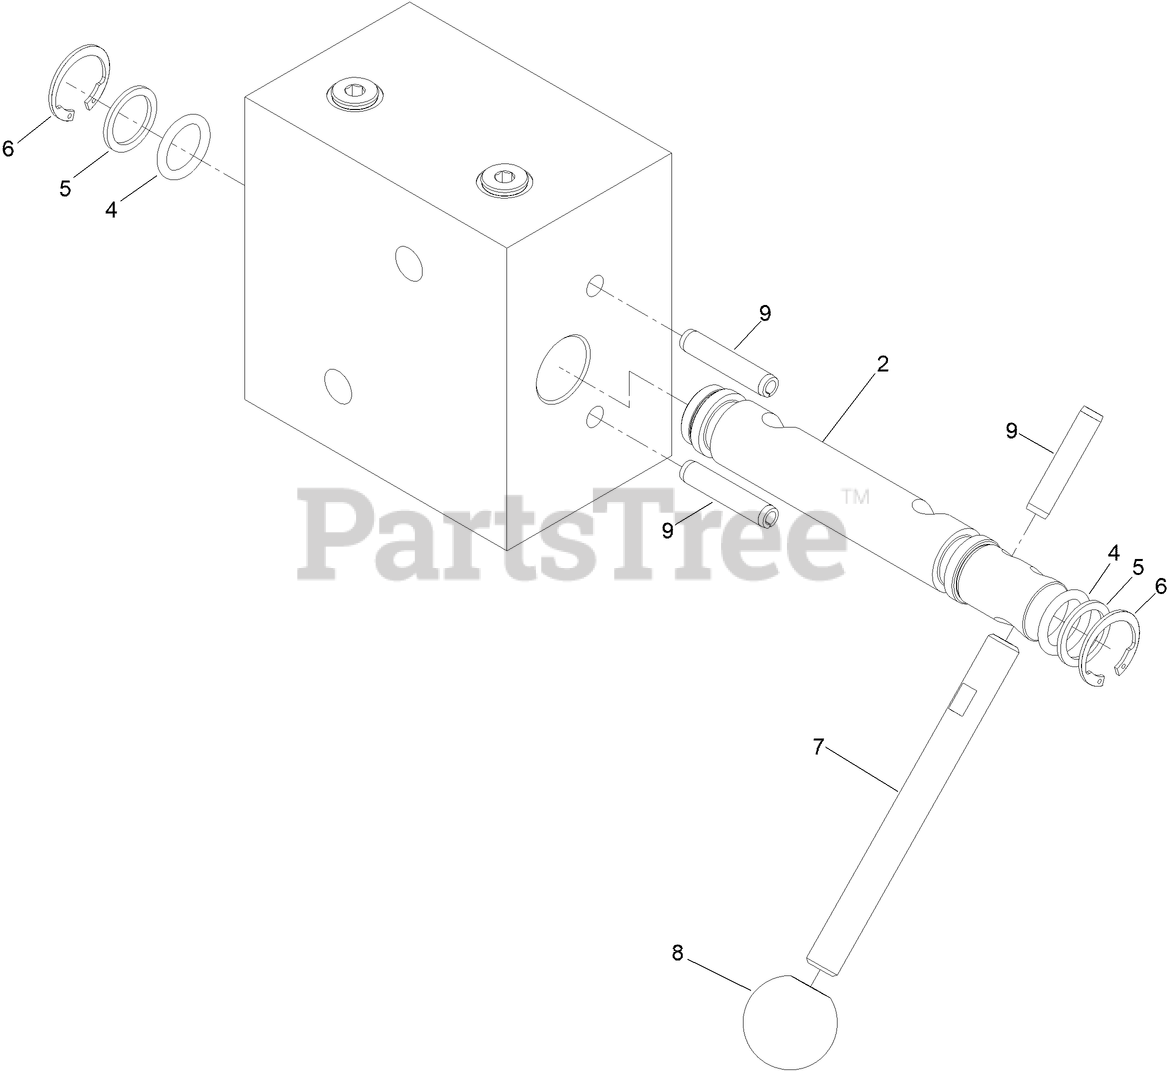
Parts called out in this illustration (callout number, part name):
2	SPOOL-SELECTOR
4	O-RING
5	RING-BACK UP
6	RING-RETAINING
7	HANDLE-SPOOL, LONG
8	KNOB-BALL, PLASTIC
9	PIN-SPRING
